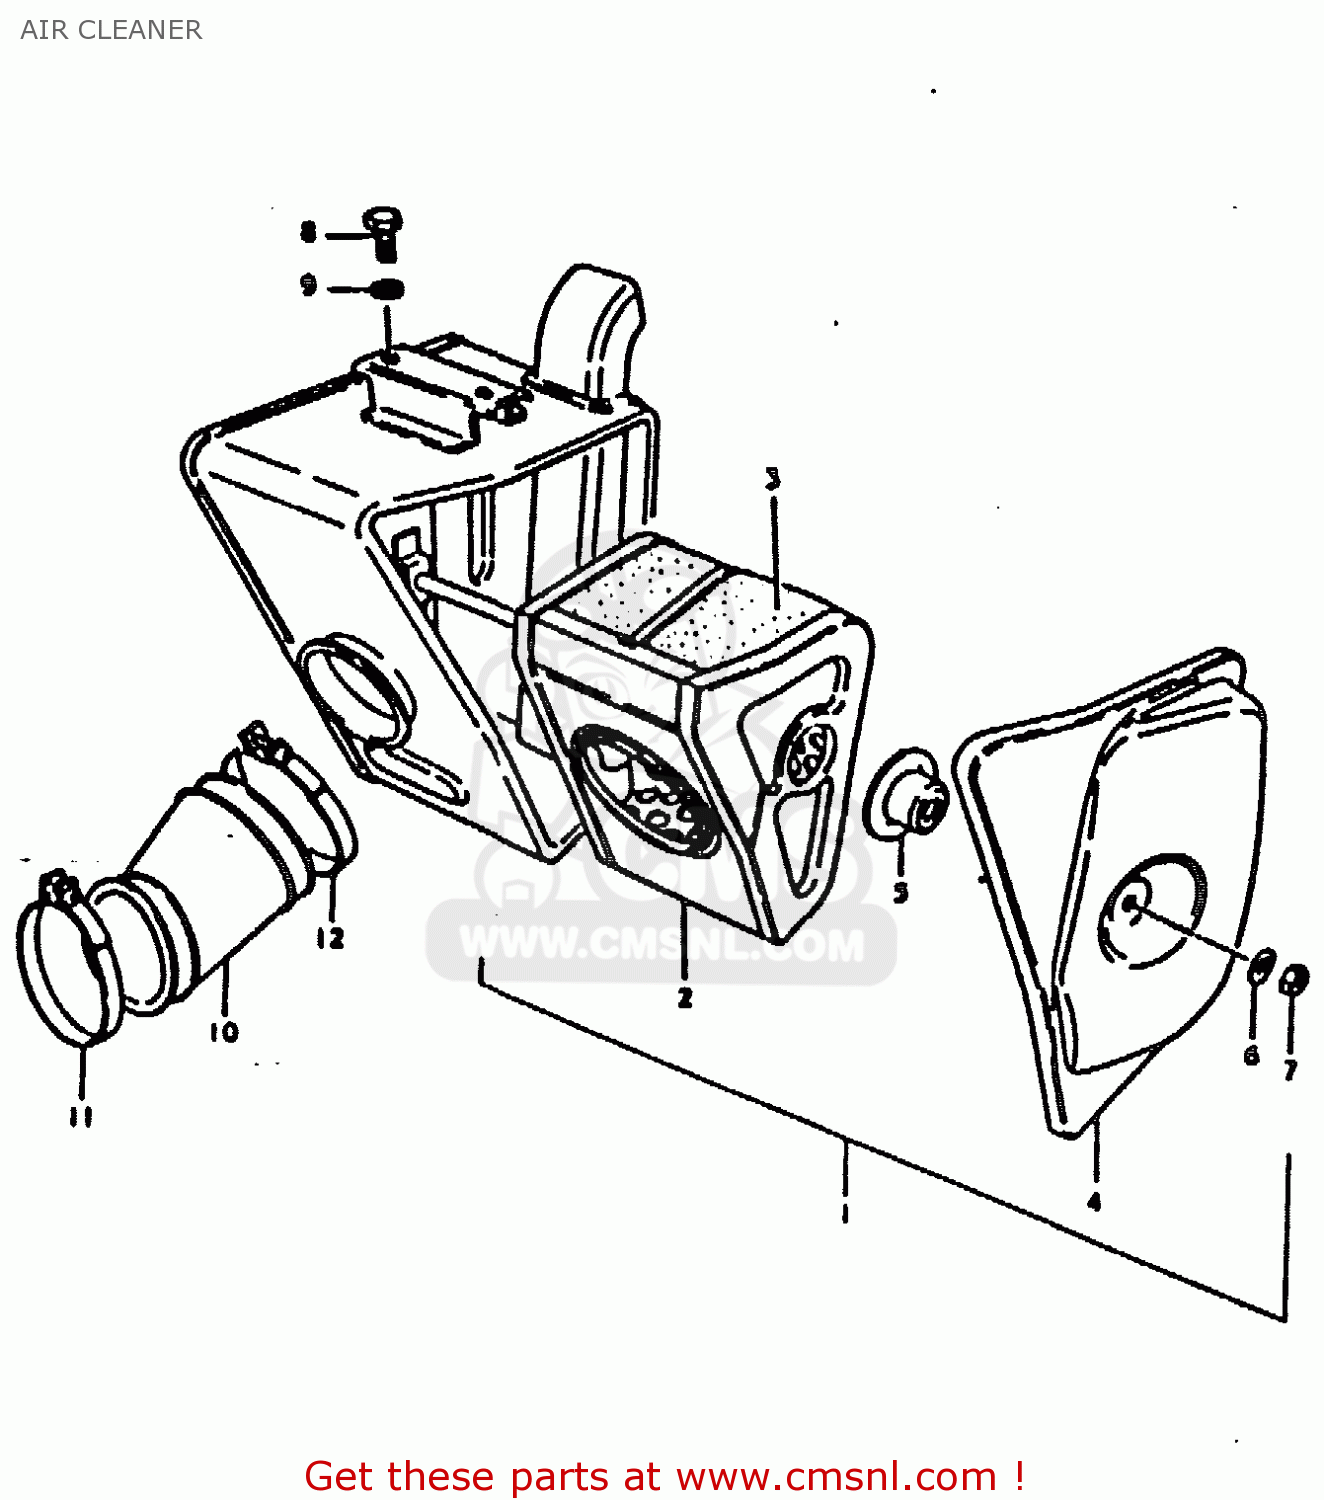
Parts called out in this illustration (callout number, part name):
1	CLEANER ASSEMBLY,AIR
2	FILTER ASSY,AIR CLEANER
3	FILTER
4	CAP
5	SPACER
6	WASHER
7	NUT
8	BOLT
9	WASHER
10	HOSE,CARBURETOR AIR INLET
11	CLAMP
12	CLAMP
